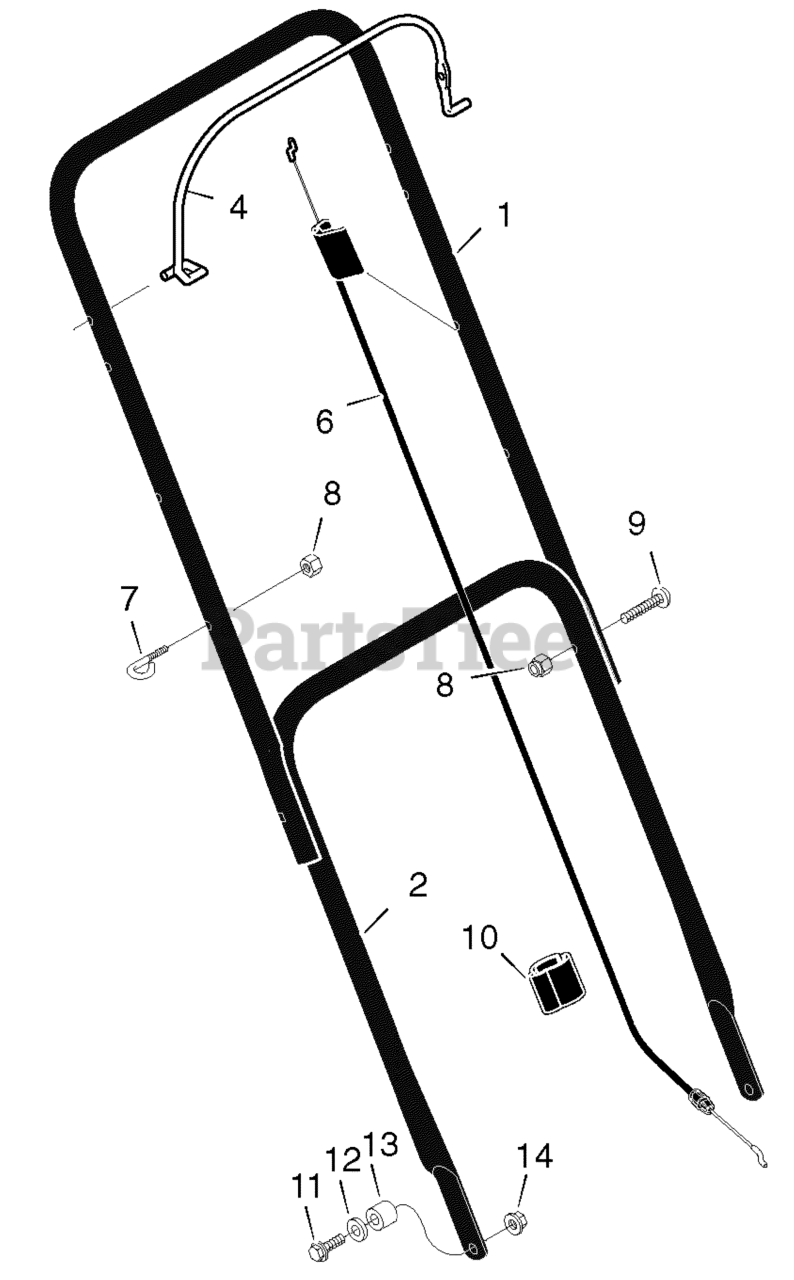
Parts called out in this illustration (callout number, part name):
1	Handle, Upper (Black)
2	Handle, Lower (Black)
4	Lever, Stop
6	Engine Stop Cable
7	Guide, Rope
8	Locknut
10	Clip, Cable
11	Bolt
12	Washer
13	Spacer
14	Nut
